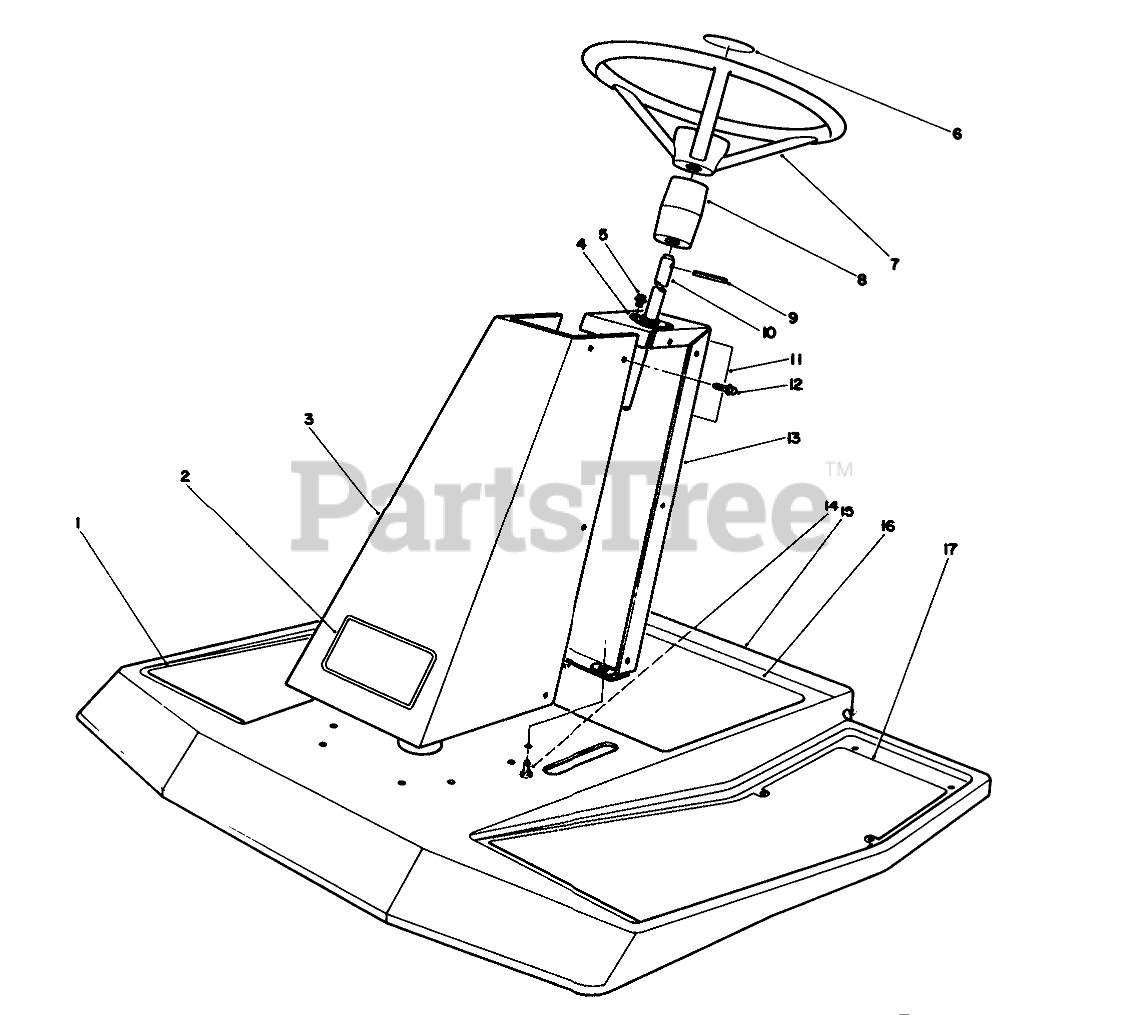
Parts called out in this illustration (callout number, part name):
1	RH FOOT TREAD
2	DECAL
3	STEERING TOWER WA R
4	GUIDE-STRG SHAFT
5	SCREW-HWHTF
6	STEERING WHEEL CAP
7	STEERING WHEEL
8	STRG. SHAFT COVER
9	PIN-ROLL
10	STEERING SHAFT WA
11	DECAL - WARNING
12	SCREW THD 1/4 20 5/8
13	Panel-Steering Tower (Incl. Ref. #11)
14	SCREW-HH
15	Pan-Floor (Incl. Ref. #1, 16, & 17)
16	DECAL - OPERATION
17	LH FOOT TREAD
